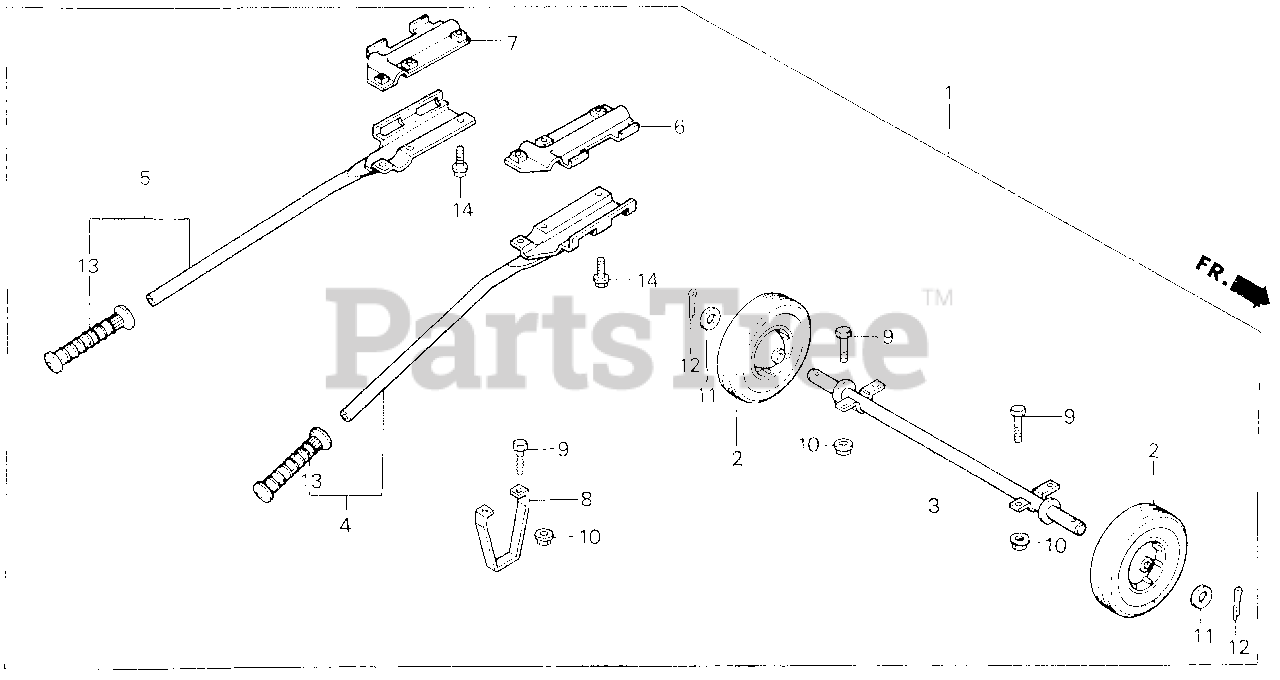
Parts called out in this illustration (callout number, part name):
1	WHEEL KIT (2-WHEELS)
2	WHEEL (10"X2.75")
3	SHAFT, WHEEL
4	HANDLE, R. (LOWER)
5	HANDLE, L. (LOWER)
6	BRACKET, R. HANDLE (UPPER)
7	BRACKET, L. HANDLE (UPPER)
9	BOLT, HEX. (8X16)
10	NUT, FLANGE (8MM)
11	WASHER, FLAT (20MM)
12	PIN, COTTER (4.0X30)
13	GRIP, R. HANDLEBAR
14	BOLT, FLANGE (8X16)
